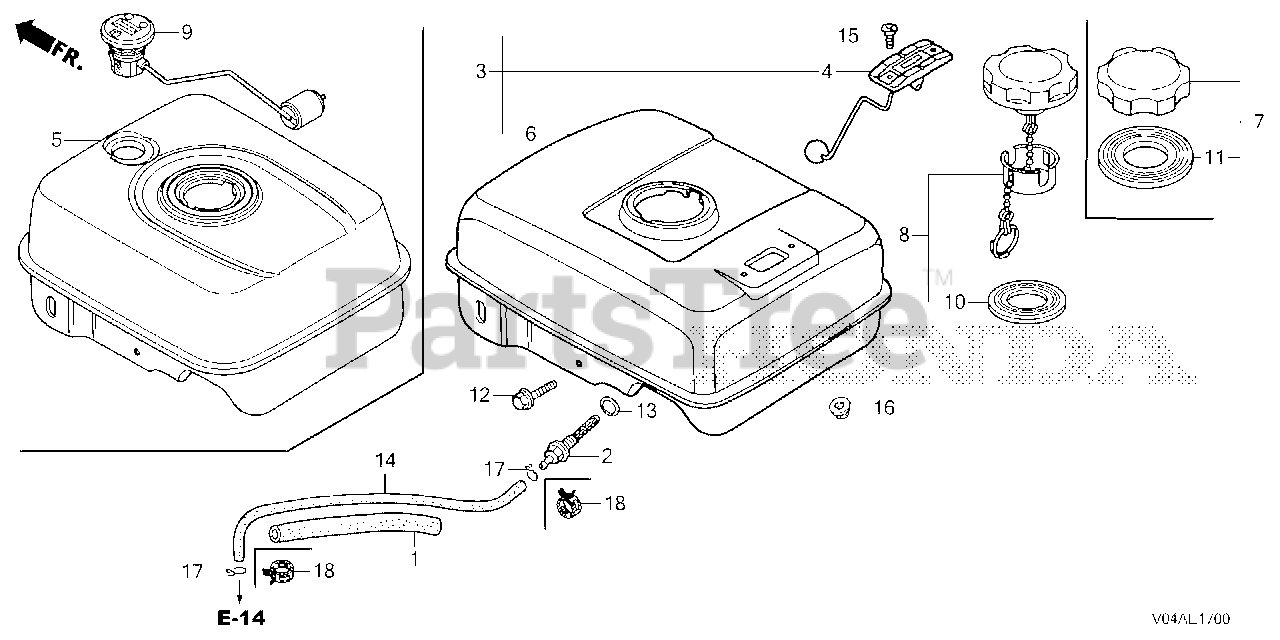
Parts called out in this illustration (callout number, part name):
1	RUBBER, SUPPORTER (107MM)
2	JOINT, FUEL TANK
5	TANK, FUEL *R280* (POWER RED)
8	CAP, FUEL FILLER
9	GAUGE ASSY., FUEL
10	GASKET, FUEL FILLER CAP (39X62X3) (RADICON)
12	BOLT, FLANGE (6X34)
13	O-RING (13.5X1.5) (ARAI)
13	O-RING (14MM) (NOK)
14	TUBE, FUEL (4.5X145) (FKM)
16	NUT, FLANGE (6MM)
18	CLAMP, TUBE (D8)
